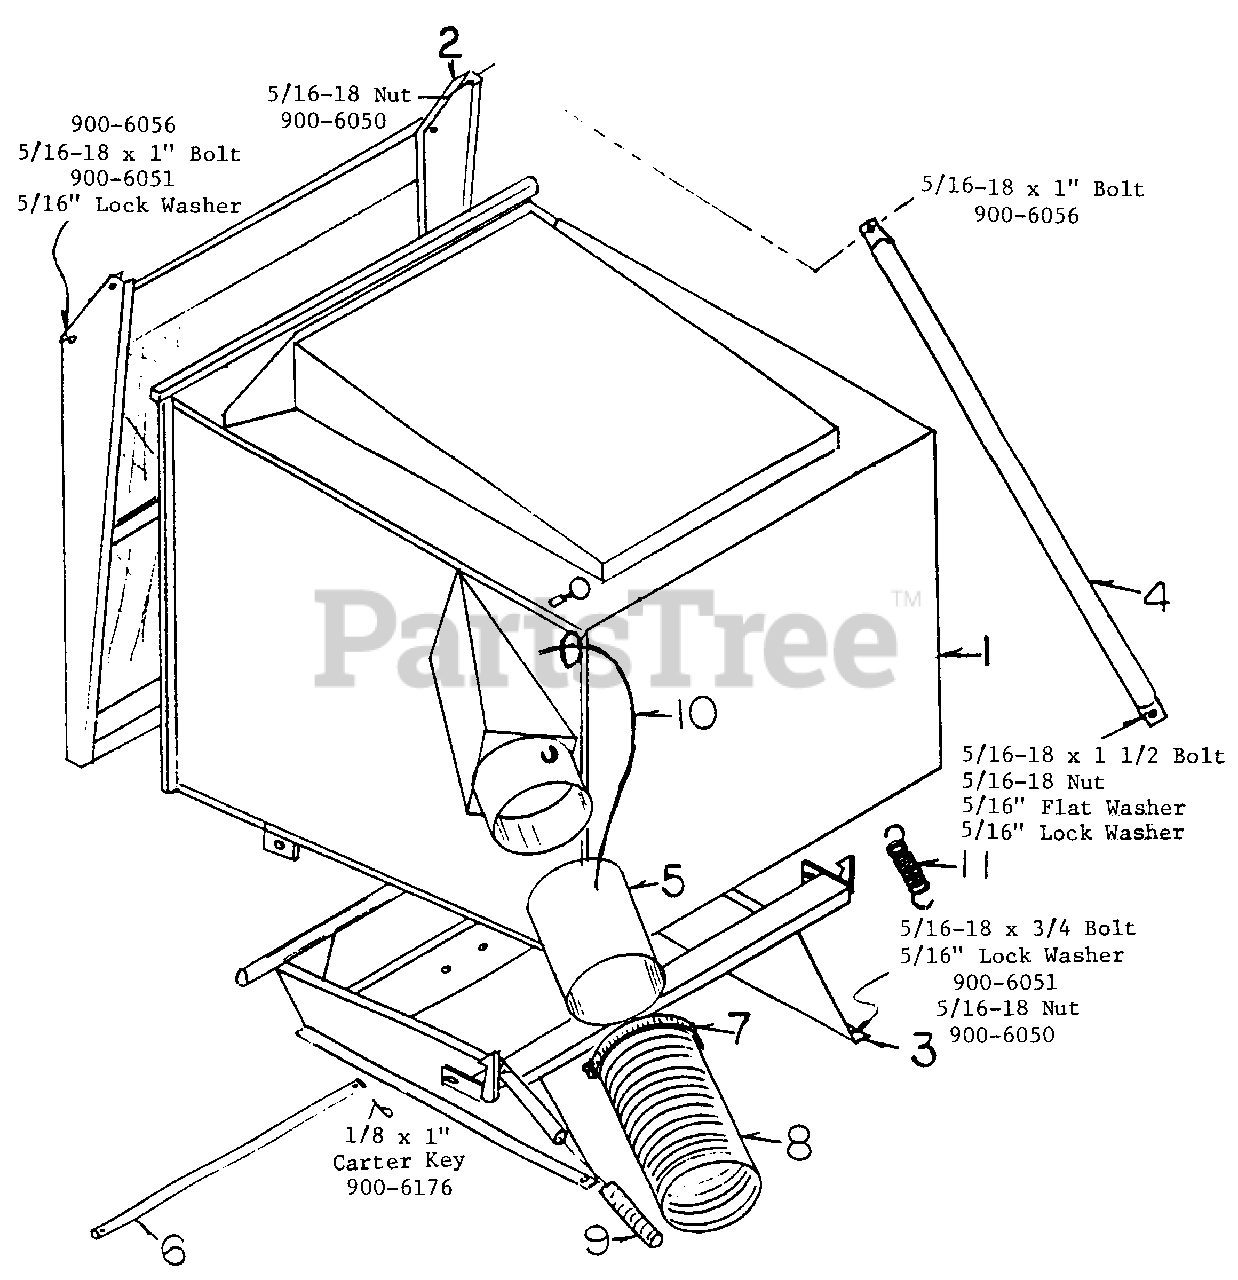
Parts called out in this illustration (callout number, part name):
1	GRASS BOX
3	BCX MOUNT
4	DOOR LINKAGE
5	MALE TUBE
8	HOSE
9	HANDLE GRIP
10	MALE TUBE ROPE
